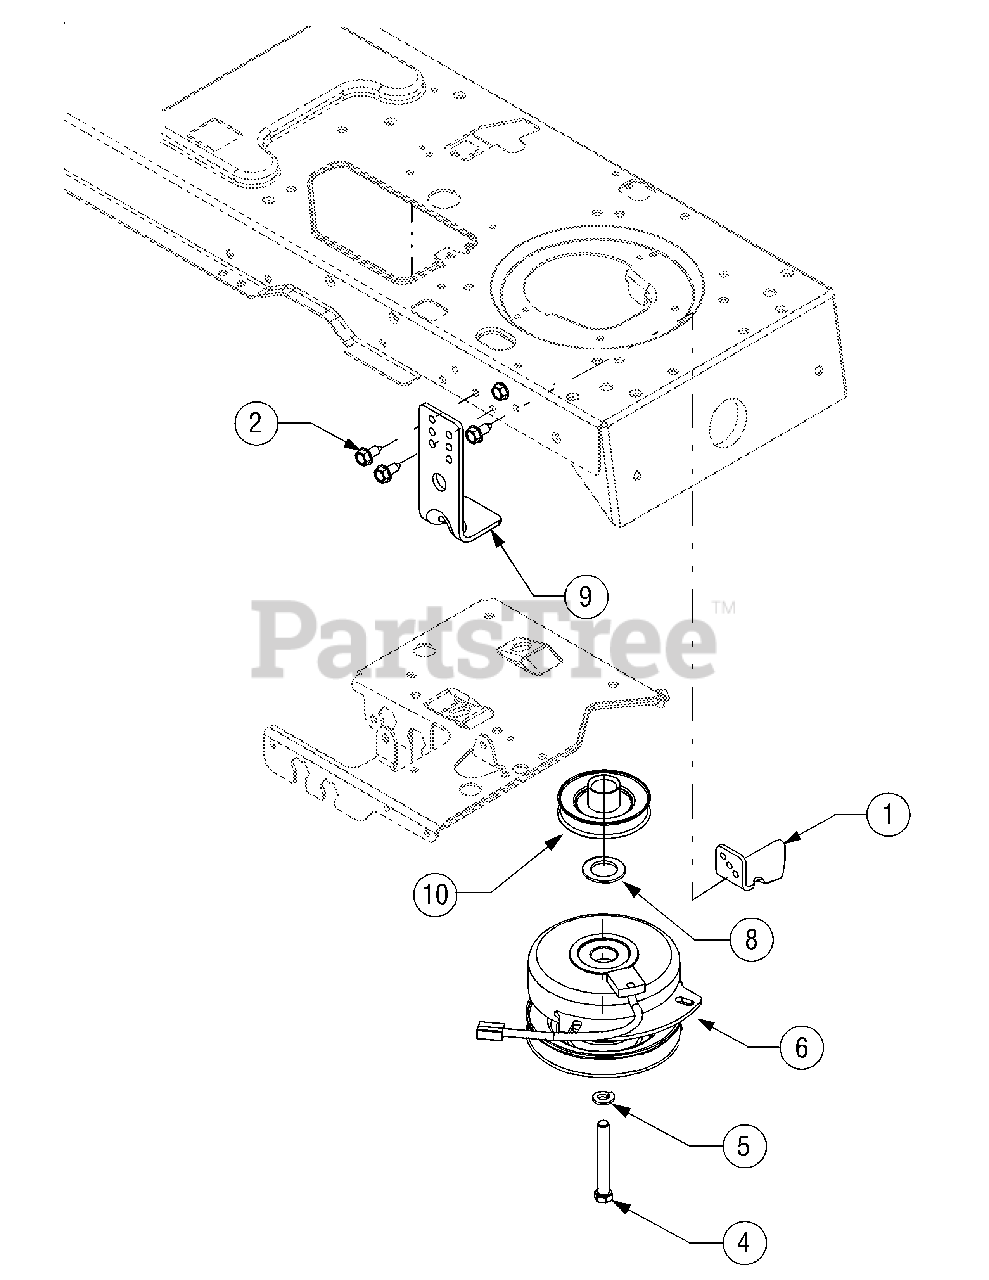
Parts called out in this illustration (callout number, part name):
2	Screw, 5/16-12, .75
4	Screw, Hex Cap, 7/16-20 x 3.50 GR5
5	Washer, Lock, 7/16
6	Clutch, PTO
8	Washer, Flat, 1.031 x 1.62 x .095
10	Pulley, 3.56"
